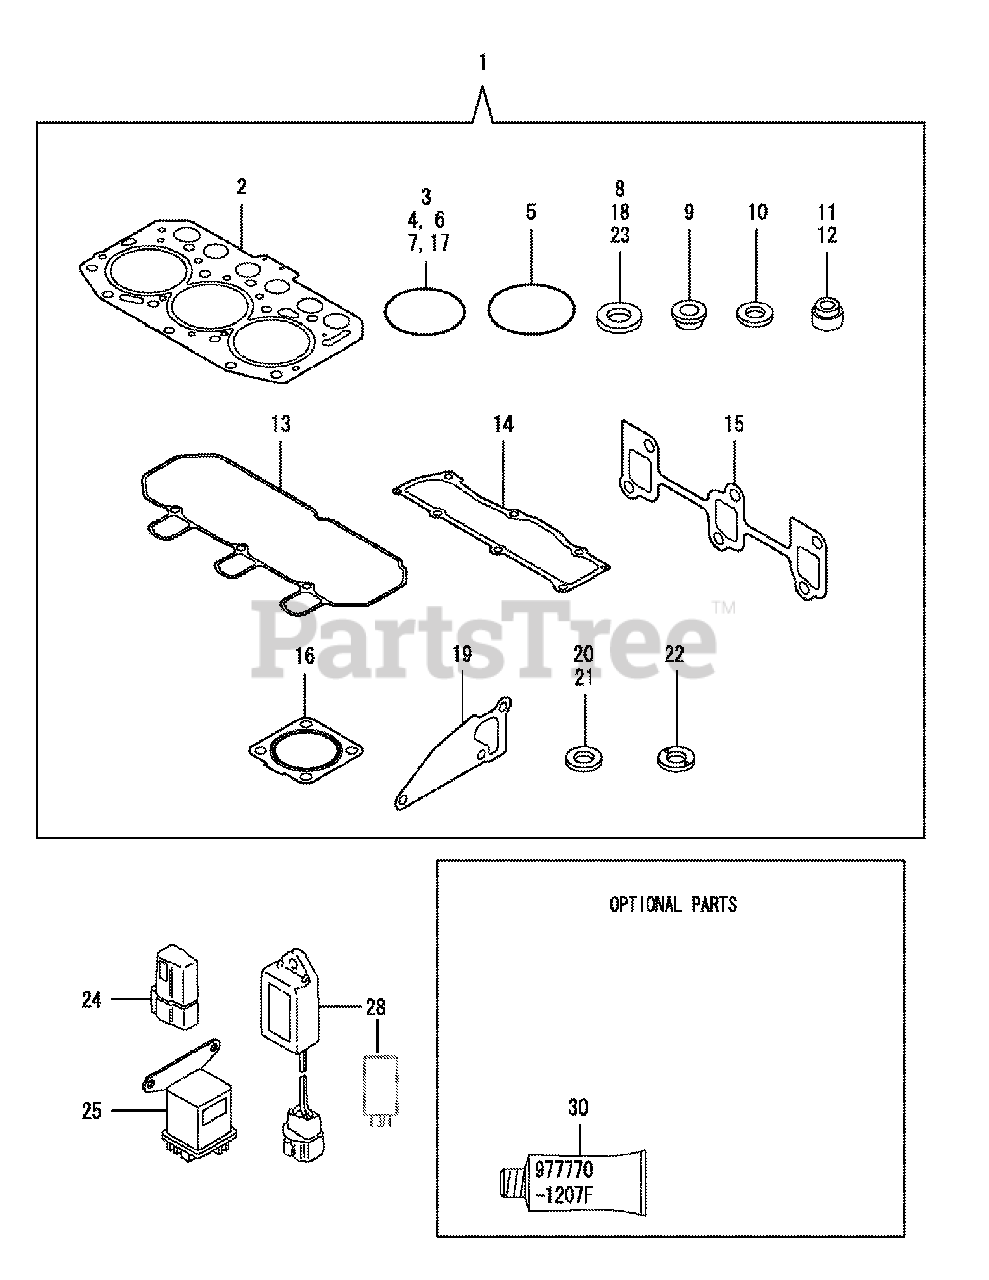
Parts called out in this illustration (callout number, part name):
2	Gasket, Cylinder Head
3	O-Ring, P 12.0
4	O-Ring, P 17.0
5	O-Ring, F.I. Pump
6	O-Ring, 1A P-32.0
7	O-Ring, 1A S-24.0
9	Protector, Nozzle
10	Gasket, Nozzle
11	Seal, Valve Stem
12	Seal, Valve Stem
13	Gasket, Bonnet
14	Gasket, Bonnet Cover
15	Gasket, Manifold
16	Gasket, Exhaust
19	Gasket, Water Pump
20	Gasket 8, Round
22	Gasket, Return
23	Seal Washer 12
25	Relay, Glow
28	Timer, Glow Plug
30	Gasket, Liquid
